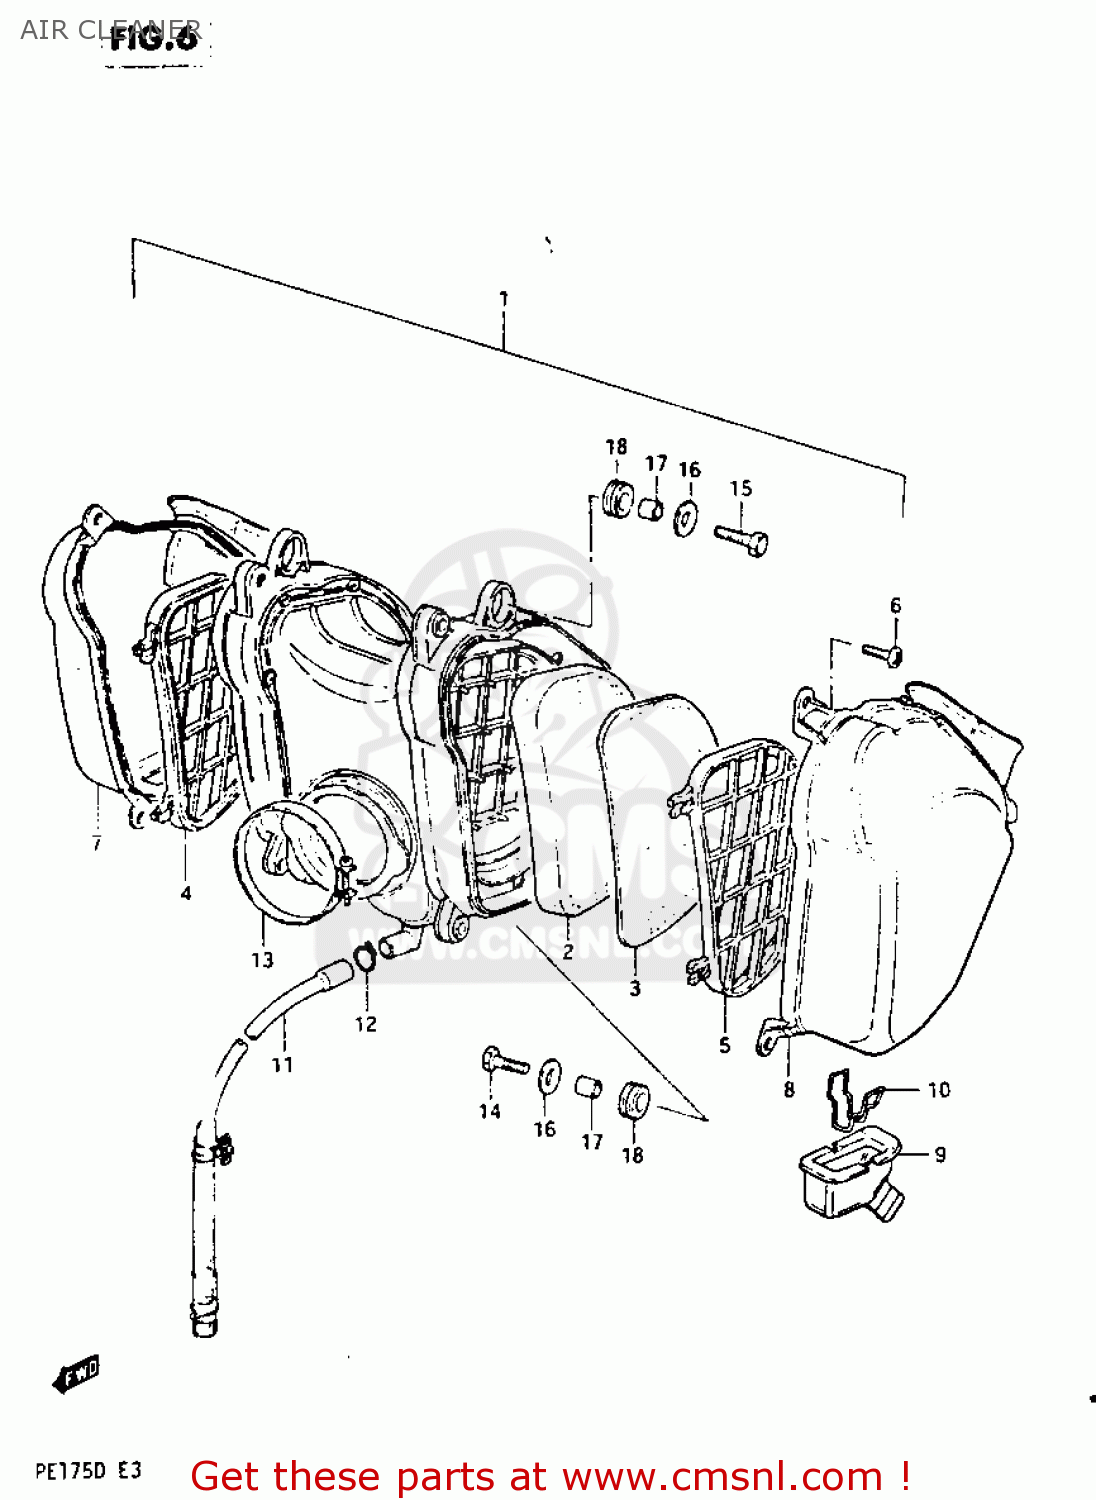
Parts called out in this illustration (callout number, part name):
1	CLEANER ASSEMBLY,AIR
2	FILTER
3	FILTER,2ND
4	HOLDER,AIR CLEANER,RIGHT
5	HOLDER,AIR CLEANER,LEFT
6	SCREW
7	CAP,AIR CLEANER,RIGHT
8	CAP,AIR CLEANER,LEFT
9	DRAIN,AIR CLEANER
10	DRAIN STOPPER
11	DRAIN TUBE
12	CLIP
13	CLAMP
14	BOLT
15	BOLT
16	WASHER(6.5X20X1.6)
17	SPACER (7X9X7)
18	CUSHION
